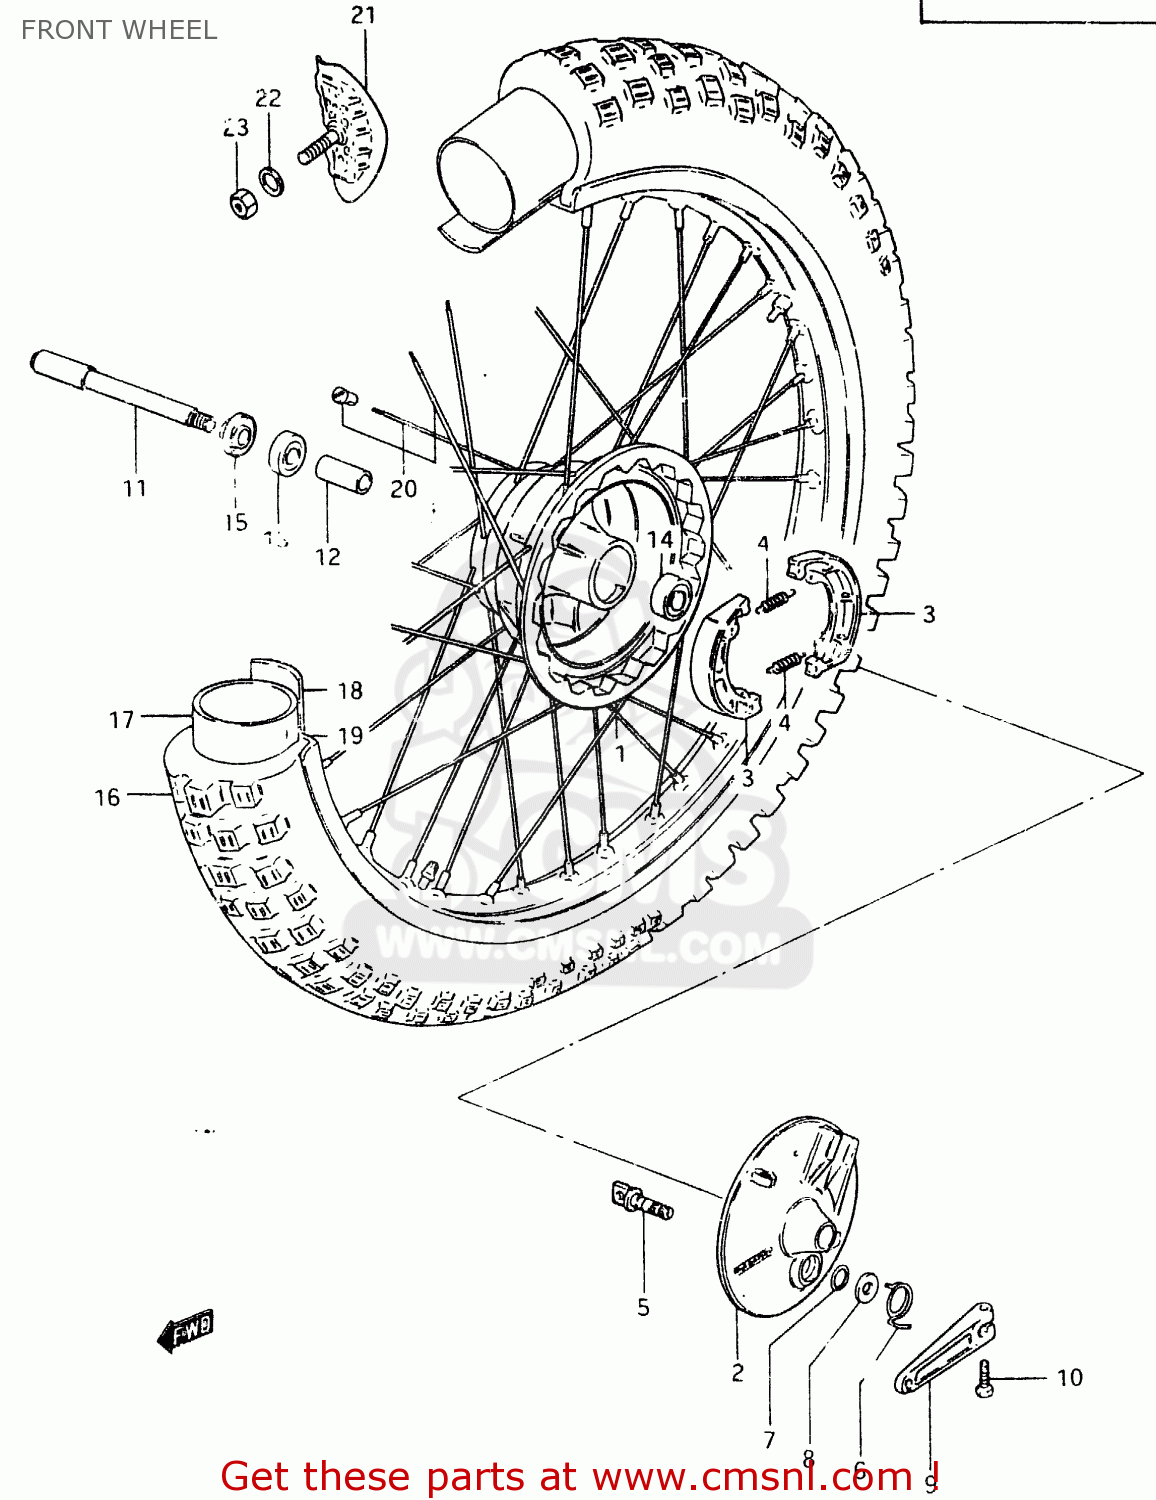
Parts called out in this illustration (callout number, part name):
1	HUB,FRONT
2	PANEL,FRONT HUB
3	SHOE,BRAKE
4	SPRING
5	CAM,FRONT BRAKE
6	SPRING
7	O RING(D:2.5,ID:11.4)
8	WASHER(12.5X20X1)
9	LEVER,FRONT BRAKE CAM
10	BOLT
11	AXLE,FRONT
12	SPACER,FRONT HUB BEARING
13	BEARING
14	BEARING
15	SPACER,FRONT AXLE,RIGHT
16	TIRE,FRONT
17	TUBE,INNER
18	PROTECTOR,WHEEL,INNER
19	RIM,FRONT WHEEL
20	SPOKE SET,FRONT
21	STOPPER,BEAD
22	WASHER
23	NUT
